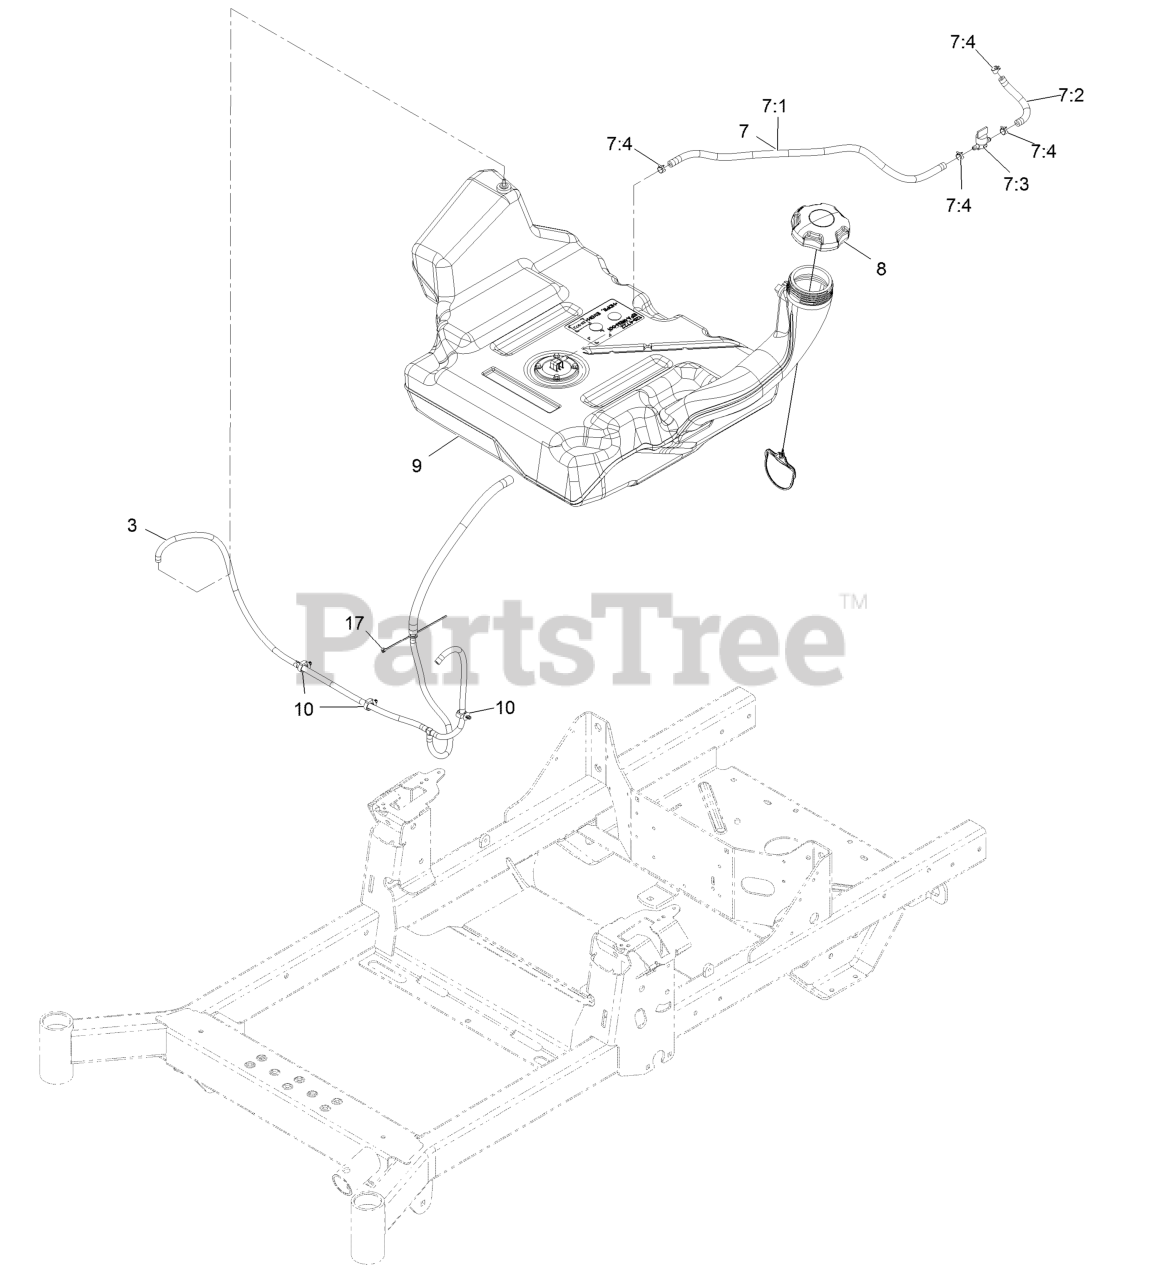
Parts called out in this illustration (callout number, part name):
3	Vent Hose ASM
7	Fuel Hose ASM
7:1	Hose-Fuel Line 24"
7:2	Hose-Fuel
7:3	Valve-Fuel
7:4	Clamp-Hose
8	Cap-Fuel
9	Tank-Fuel
17	Tie-Cable 5 1/2 (Small)
